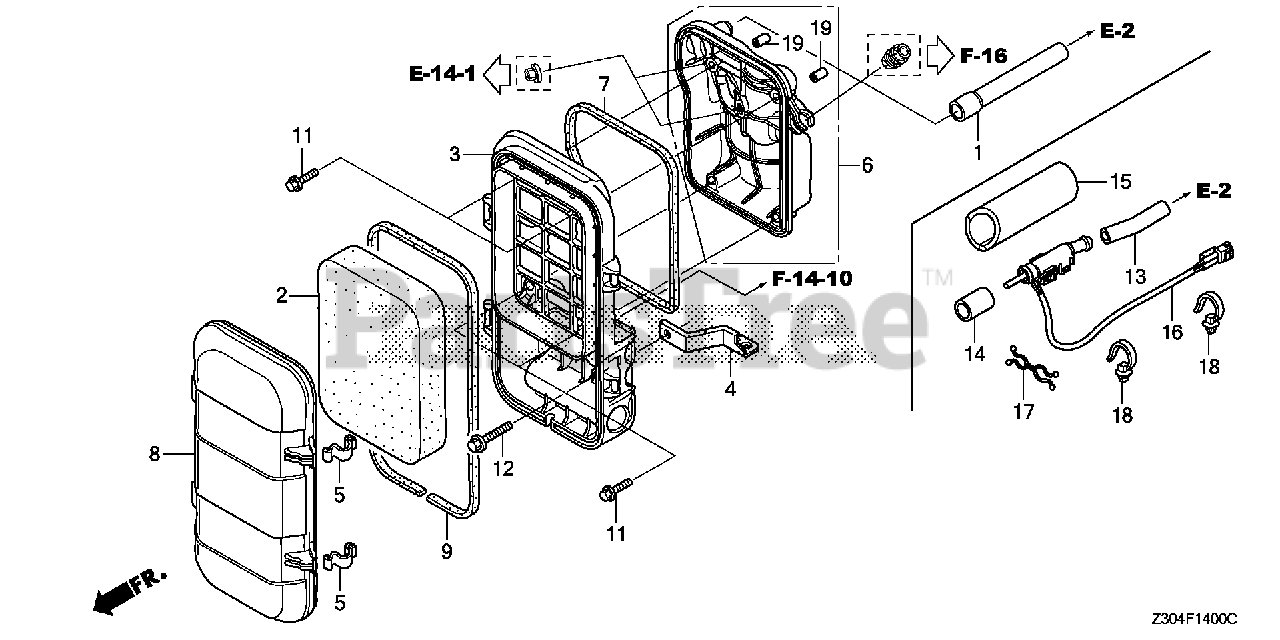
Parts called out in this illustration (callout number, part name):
1	TUBE, BREATHER
2	ELEMENT, AIR CLEANER
3	HOUSING, AIR CLEANER
4	STAY, AIR CLEANER
5	SPRING, AIR CLEANER HOUSING LID
6	BASE, AIR CLEANER
7	SEAL, AIR CLEANER HOUSING
8	COVER, AIR CLEANER
9	SEAL, AIR CLEANER COVER
11	BOLT, FLANGE (5X18)
12	BOLT, FLANGE (6X32)
19	COLLAR, AIR CLEANER
